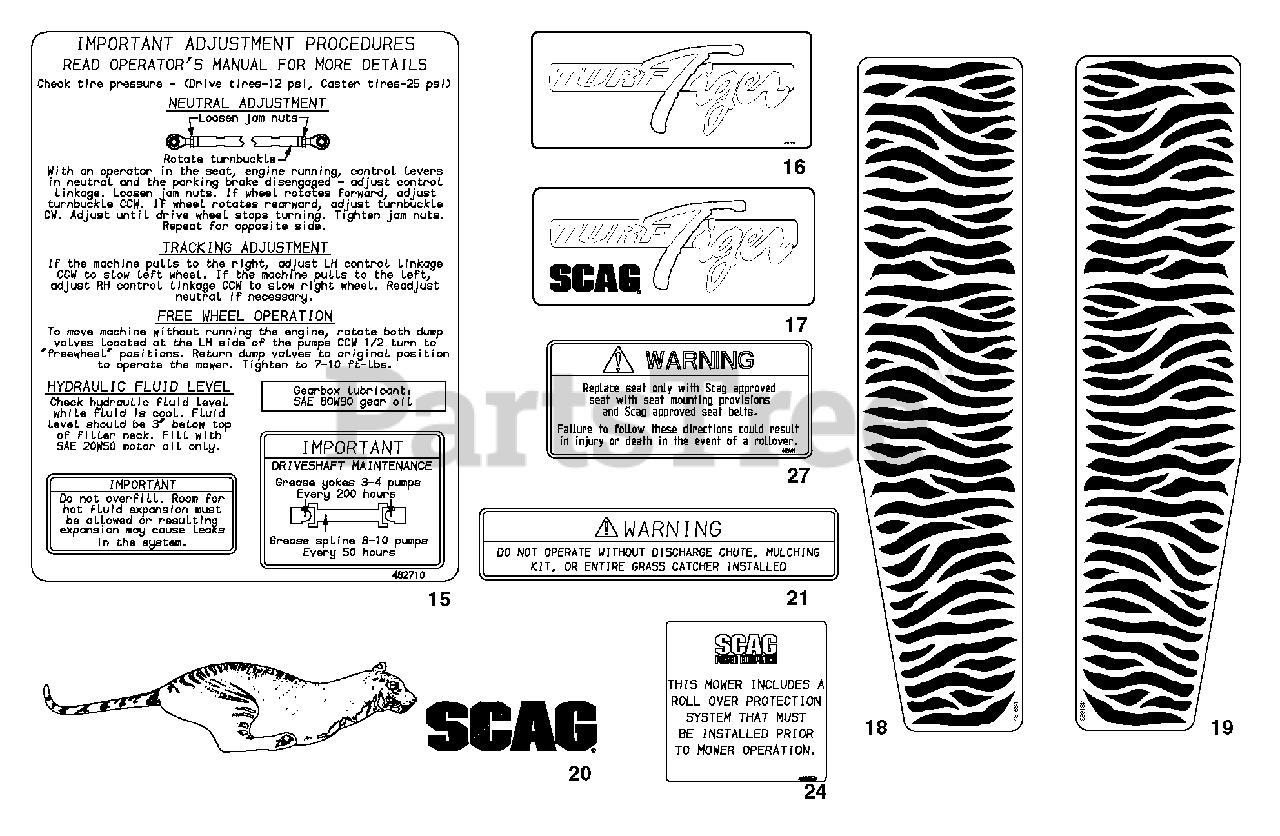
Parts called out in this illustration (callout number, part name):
15	Decal, Seat Support
16	Decal, Turf Tiger
17	Decal, Turf Tiger
18	Decal, Stripes-RH
19	Decal, Stripes-LH
20	Decal, Tiger
21	Decal, Warning
24	Decal, ROPS
27	Decal, Seat Replacement
